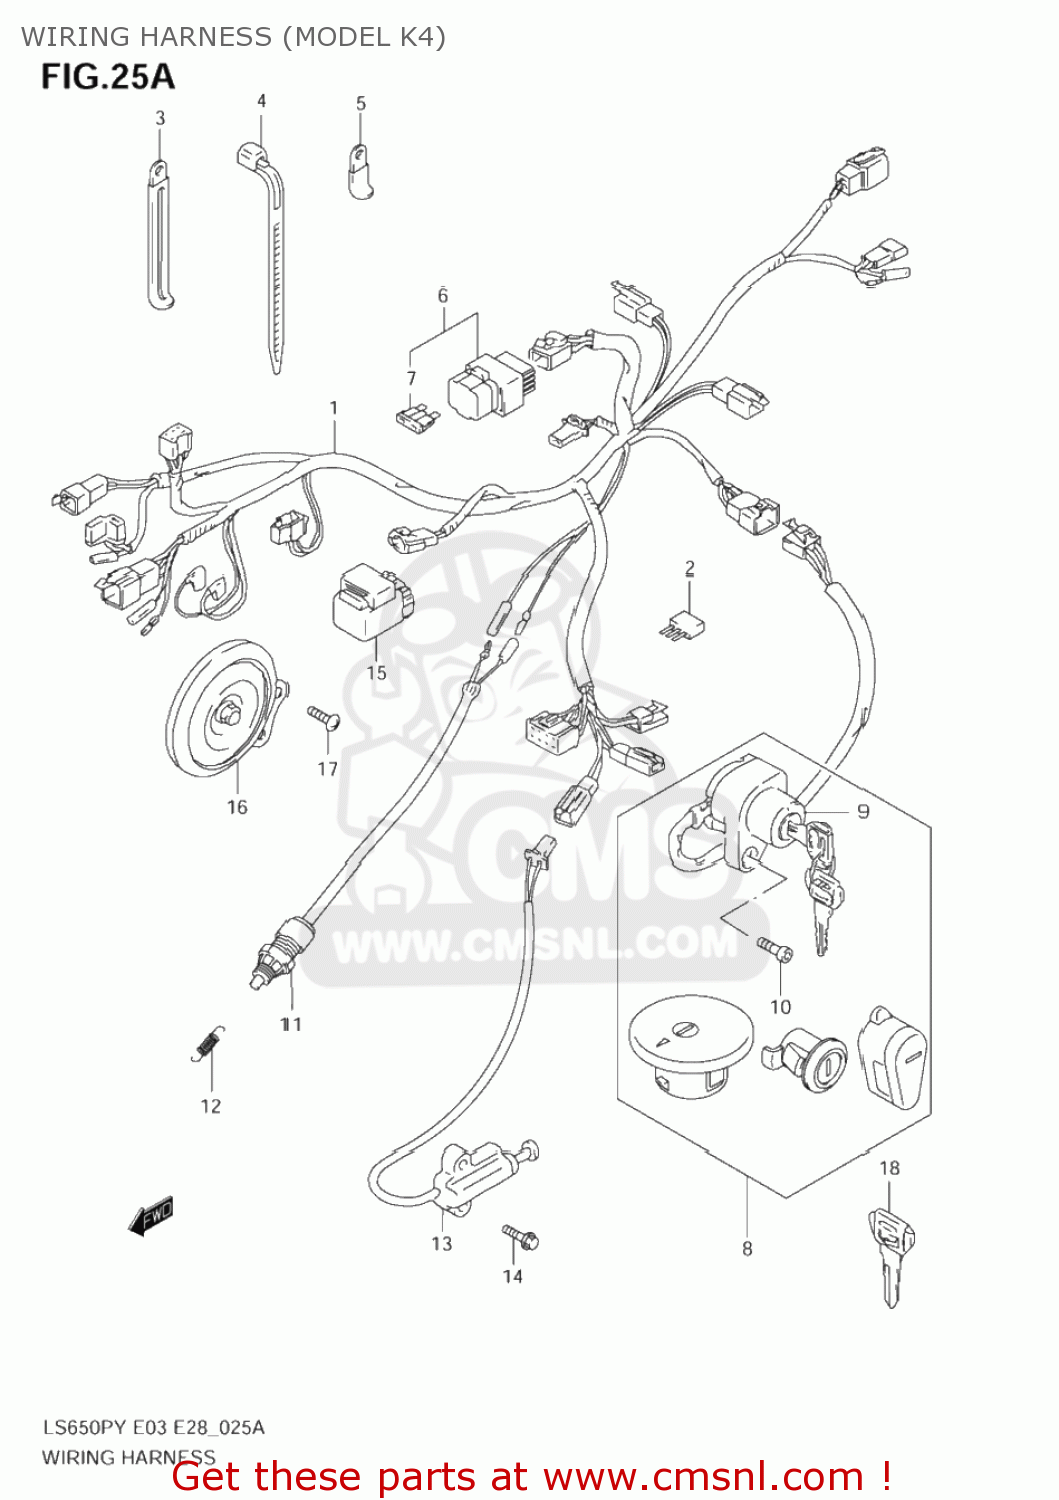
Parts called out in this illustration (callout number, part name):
1	HARNESS,WIRING
2	DIODE(STANLEY DE8804)
3	CLAMP(L:80)
4	CLAMP(L:125)
5	CLAMP
6	BOX ASSY,FUSE
7	FUSE(20A)
8	LOCK SET
9	SWITCH ASSY,IGNITION
10	BOLT
11	SWITCH ASSY,STOP LAMP
12	SPRING
13	SWITCH ASSY,SIDE STAND WARNING
14	BOLT
15	RELAY ASSY
16	HORN ASSY
17	SCREW 6X12
18	KEY,BLANK(TYPE:C)
